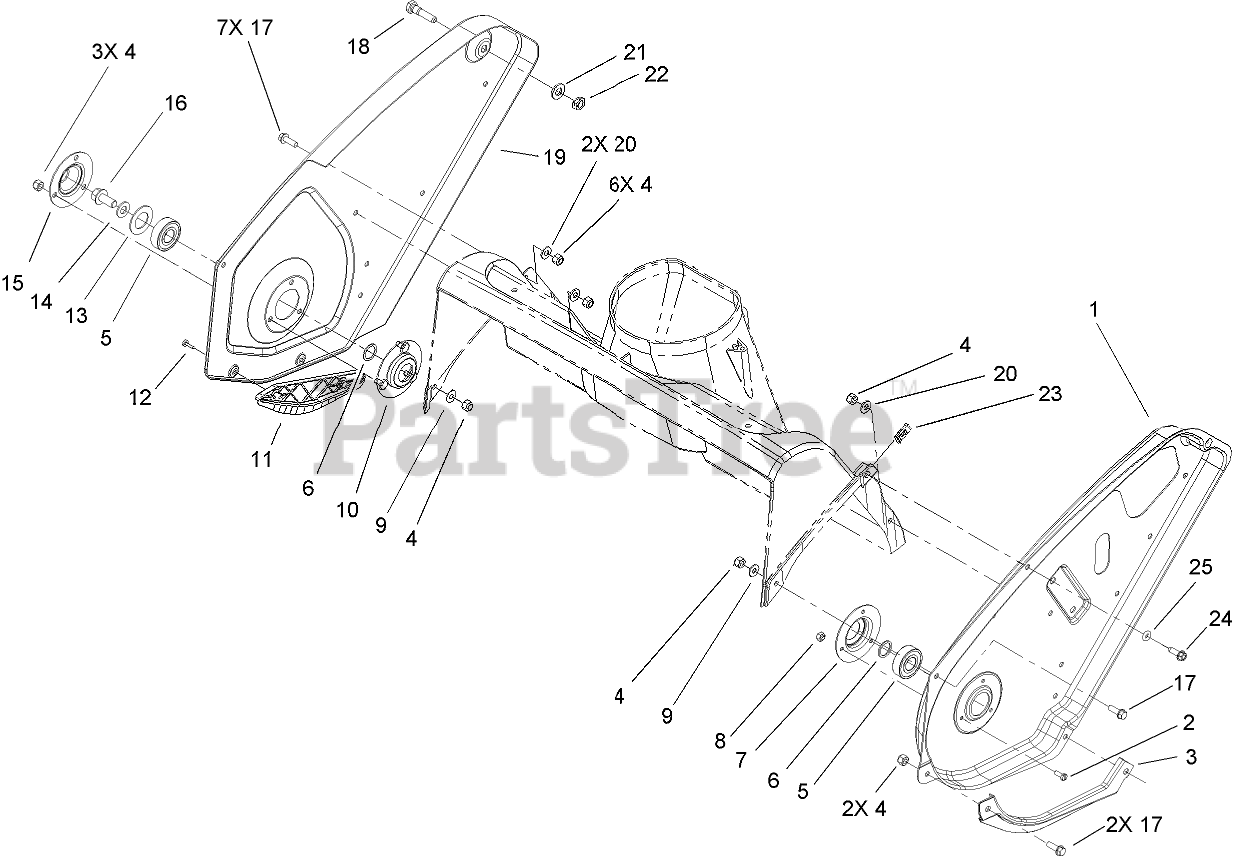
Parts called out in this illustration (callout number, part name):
1	SIDEPLATE-LH
2	SCREW-SHH
3	GUARD-ROTOR, LH
4	NUT-LOCK, NI
5	BEARING-BALL
6	WASHER-THRUST
7	FLANGE-BEARING
8	NUT-LOCK, NI
9	WASHER-FLAT
10	FLANGE-BEARING
11	GUARD-ROTOR, RH
12	SCREW-PPH
13	WASHER-RUBBER
14	WASHER-FLAT
15	RETAINER-BEARING
16	SCREW-HHF
17	SCREW-HWH
18	PIN-ROTOR
19	SIDEPLATE-RH
20	WASHER-FLAT
21	WASHER-FLAT
22	NUT-LOCK, CONE
23	NUT-SPEED
24	SCREW-HWHTF
25	O-RING
